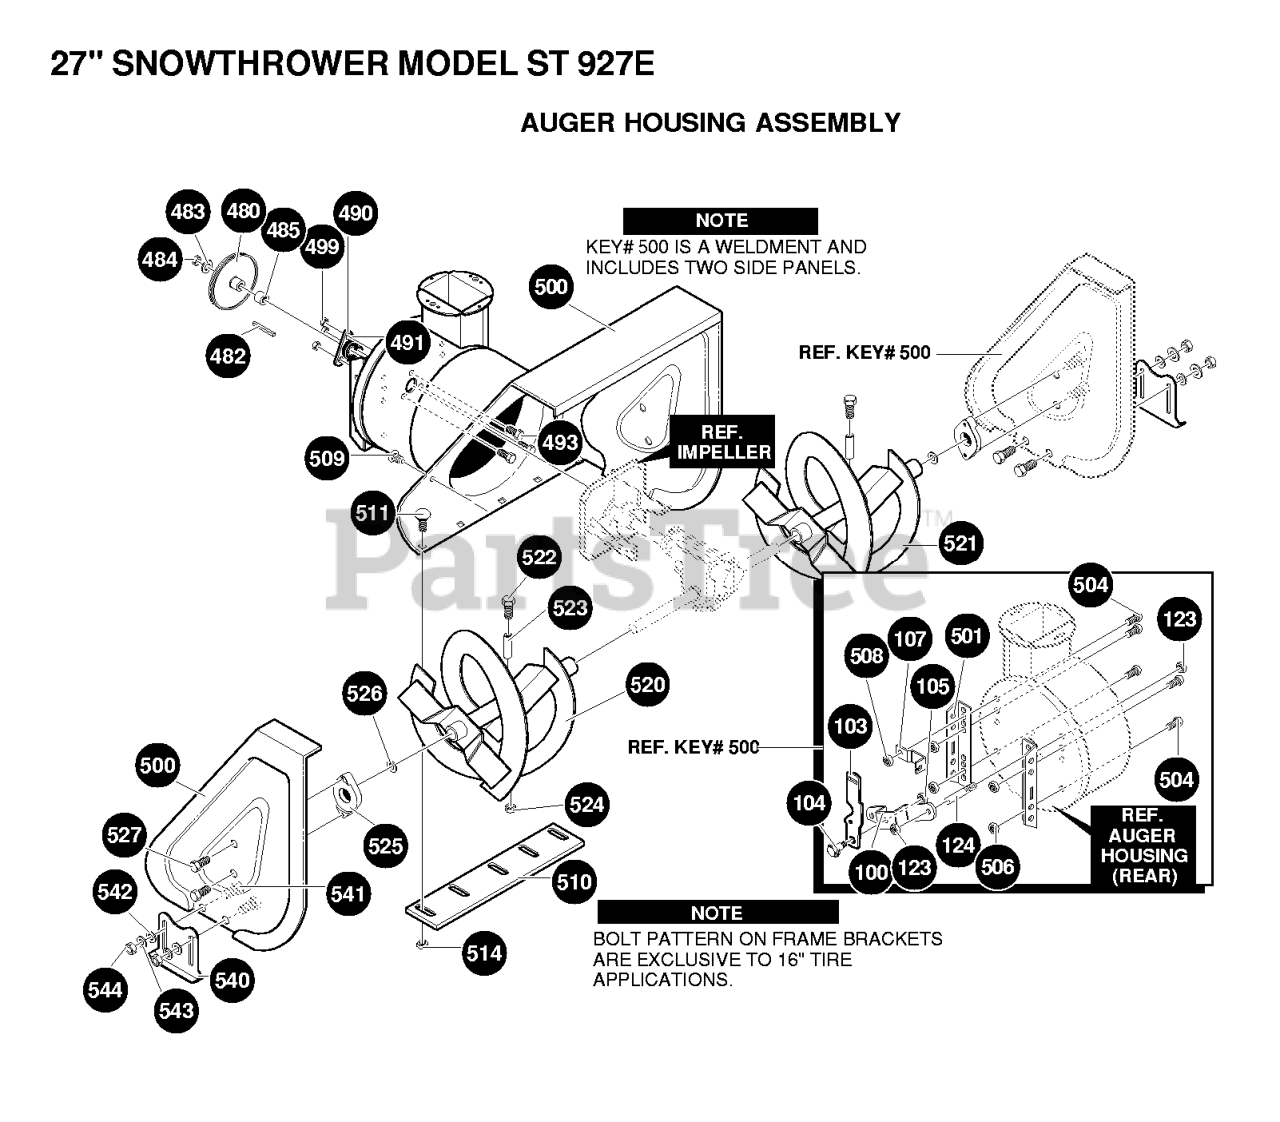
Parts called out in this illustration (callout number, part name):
100	PLATE, CLUTCH ARM MT.
103	BRACKET, IDLER
104	Bolt, .497 x .138
105	NUT, 3/8-16 REGHXCTRLK
107	BRACKET, CABLE MT.
123	NUT, 3/8-16 REGHXCTRLK
124	STUD, BRAKE ARM
125	WASHER, REGSPTLK.393X.68X
480	PULLEY, V4L 8.40 OD
482	SQUARE KEY
484	NUT, 1/2-20 REGHXCTRLK
485	SPACER, SLEV .676X1.00X.53
491	BEARING
493	SCREW, 5/16-18X .75 HHC
499	NUT, 5/16-18
500	HOUSING ASSEMBLY/24"
501	BRKT, MOUNT
506	NUT, 3/8-16 REGHXCTRLK
508	NUT, 3/8-16 REGHXCTRLK
509	PLUG, CHRISTMAS TREE
510	BLADE, SCRAPER, MF 27"
514	NUT, 5/16-18
520	AUGER, ASSY LH 25"
521	AUGER, ASSY RH 25"
522	BOLT, SHEAR 703057
524	NUT, 1/4-20 REGHEXCTRLK
525	BEARING, AUGER SHAFT
527	SCREW, 5/16-18X .75 WAHHT
540	SKID, HEIGHT ADJUST
542	WASHER, FLAT .344X .69X.
543	WASHER, HVSPTLK .328X.60X
544	NUT, 5/16-18 REGHEX
